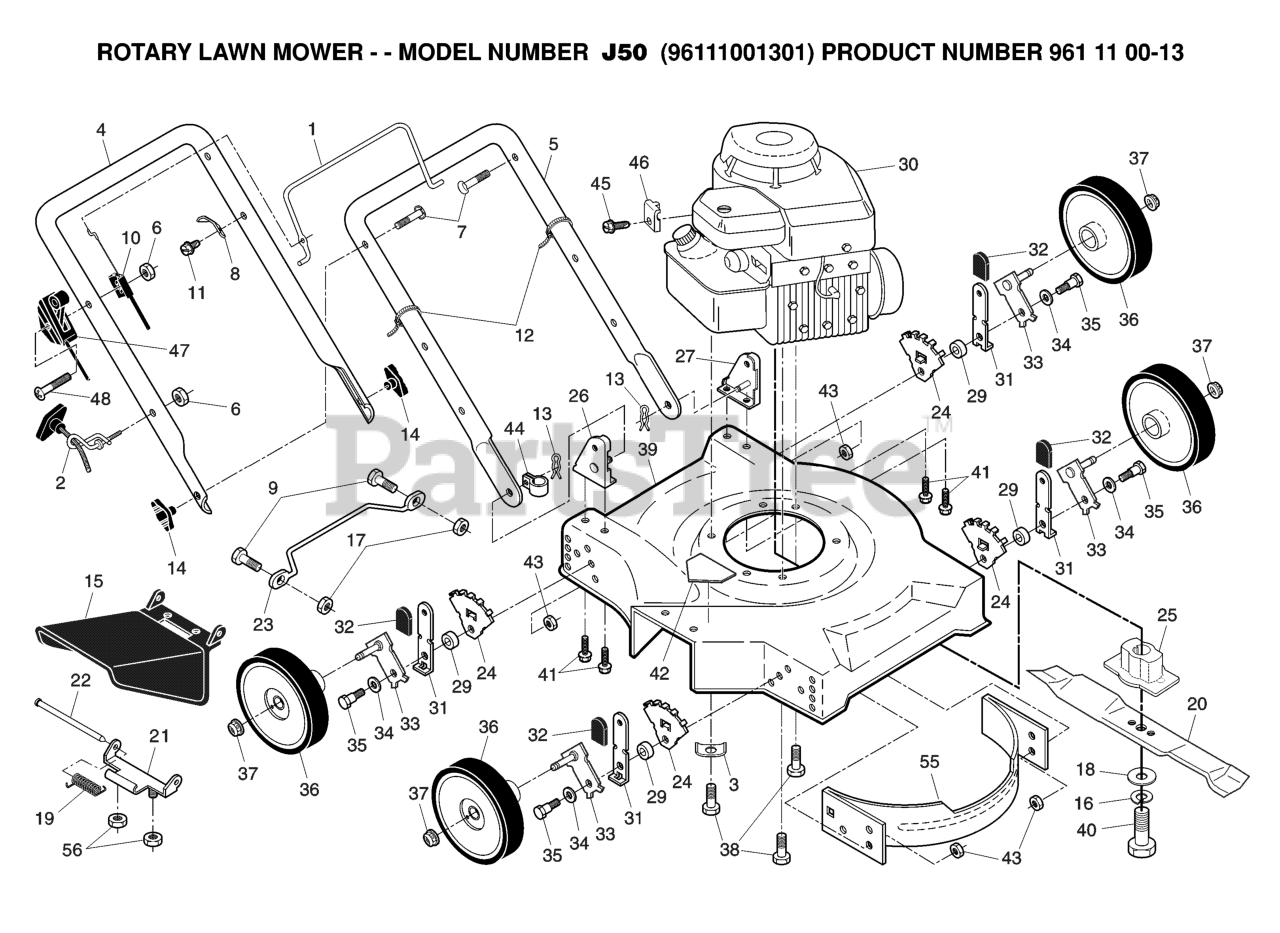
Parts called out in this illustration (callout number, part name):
1	BAIL.CONT.D.STRAIGHT.PUSH.BLK
2	RB GUIDE.ROPE.STD.BLK.ZIN WSL
3	WASHER.ENGINE.BZP
4	HANDLE.UPPER.FGD/PUSH.BLACK
5	LOWER HANDLE
6	NUT
7	BOLT, HANDLE 5/16-18X1.75
8	BRACKET UPSTOP
9	REPL BY 817 02 10-08
10	CABLE.CONTROL.MZR.RH.SP/PUSH
12	TIE GUIDE
13	HAIRPIN COTTER
14	KNOB, DEFLECTOR
16	LOCKWASHER
18	WASHER,HARDEN
19	SPRING TENSION
20	BLADE.20.MULCH.(50DK,6020MD)
21	HINGE DEFLECTOR
24	WHEEL ADJUST BRACKET
25	BLADE ADAPTOR
26	HANDLE BRACKET ASM. RH
27	HANDLE BRACKET ASM. LH
29	RP SPACER HT ADJ
31	SELECTOR SPRING
33	AXLE, REAR
34	WASHER.BELLEVILLE (3 2 LB)
35	BOLT
36	WHEEL.8X1.75.GRY.BRK.5SPK.MAG
37	HEX FLANGE LOCKNT
38	BOLT 3/8-16X1-1/8
40	SCREW, HEX HD 3/8-24 X 1-3/8
41	SCREW.5/16-18X3/4
42	DECAL.INTERNATIONL.CUTFINGER
43	LOCKNUT PM
44	CLIP.CABLE.BLK
45	SCREW.HEX.HEAD.WASHER.10-16
46	CABLE CLAMP(ENGINE)
47	THROTTLE CONTROL
55	FRONT BAFFLE
56	LOCKNUT.NYLOC.1/4-20
